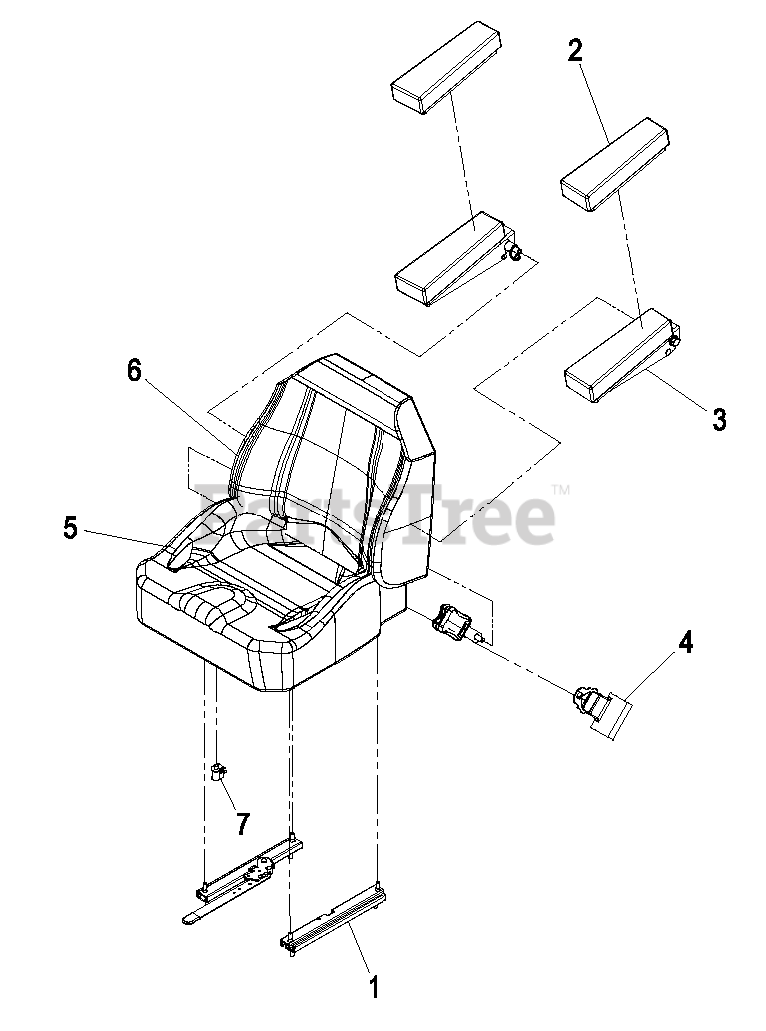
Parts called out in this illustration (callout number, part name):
1	SEAT TRACK SET
2	SET,ARM REST PADS
3	KIT,ARM REST SET
4	SEAT BELT KIT
5	COVER,CUSHION
6	COVER,BACK
7	SWITCH-BAIL
